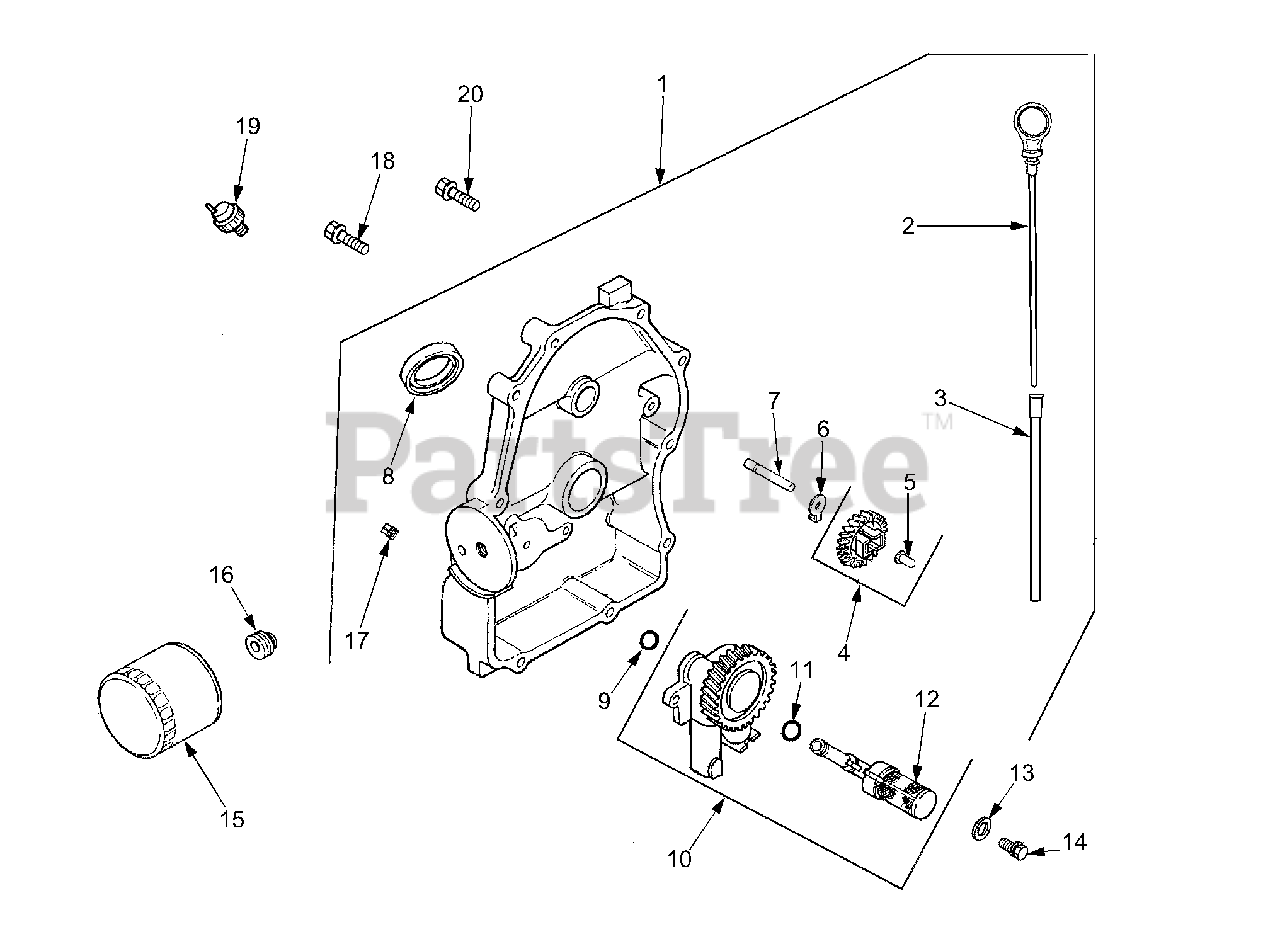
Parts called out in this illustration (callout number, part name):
1	Plate, Closure Assembly
3	Tube, Dipstick
4	Kit, Governor Gear
5	Pin, Governor Regulating
6	Tab, Locking
7	Shaft, Governor Gear
8	Seal, Oil (PTO End)
10	Oil Pump Assembly
11	O-Ring, Oil Pick-Up
12	Pick-Up, Oil
13	Washer, Plain
14	Screw, Hex Flange M6 x 1 x 25
15	Filter, Oil
16	Nipple, Oil Filter
17	Plug, Pipe 1/8"
18	Screw, Hex Flange M8 x 1.25 x 45
19	Switch, Pressure
20	Screw, Hex Flange M8 x 1.25 x 45
